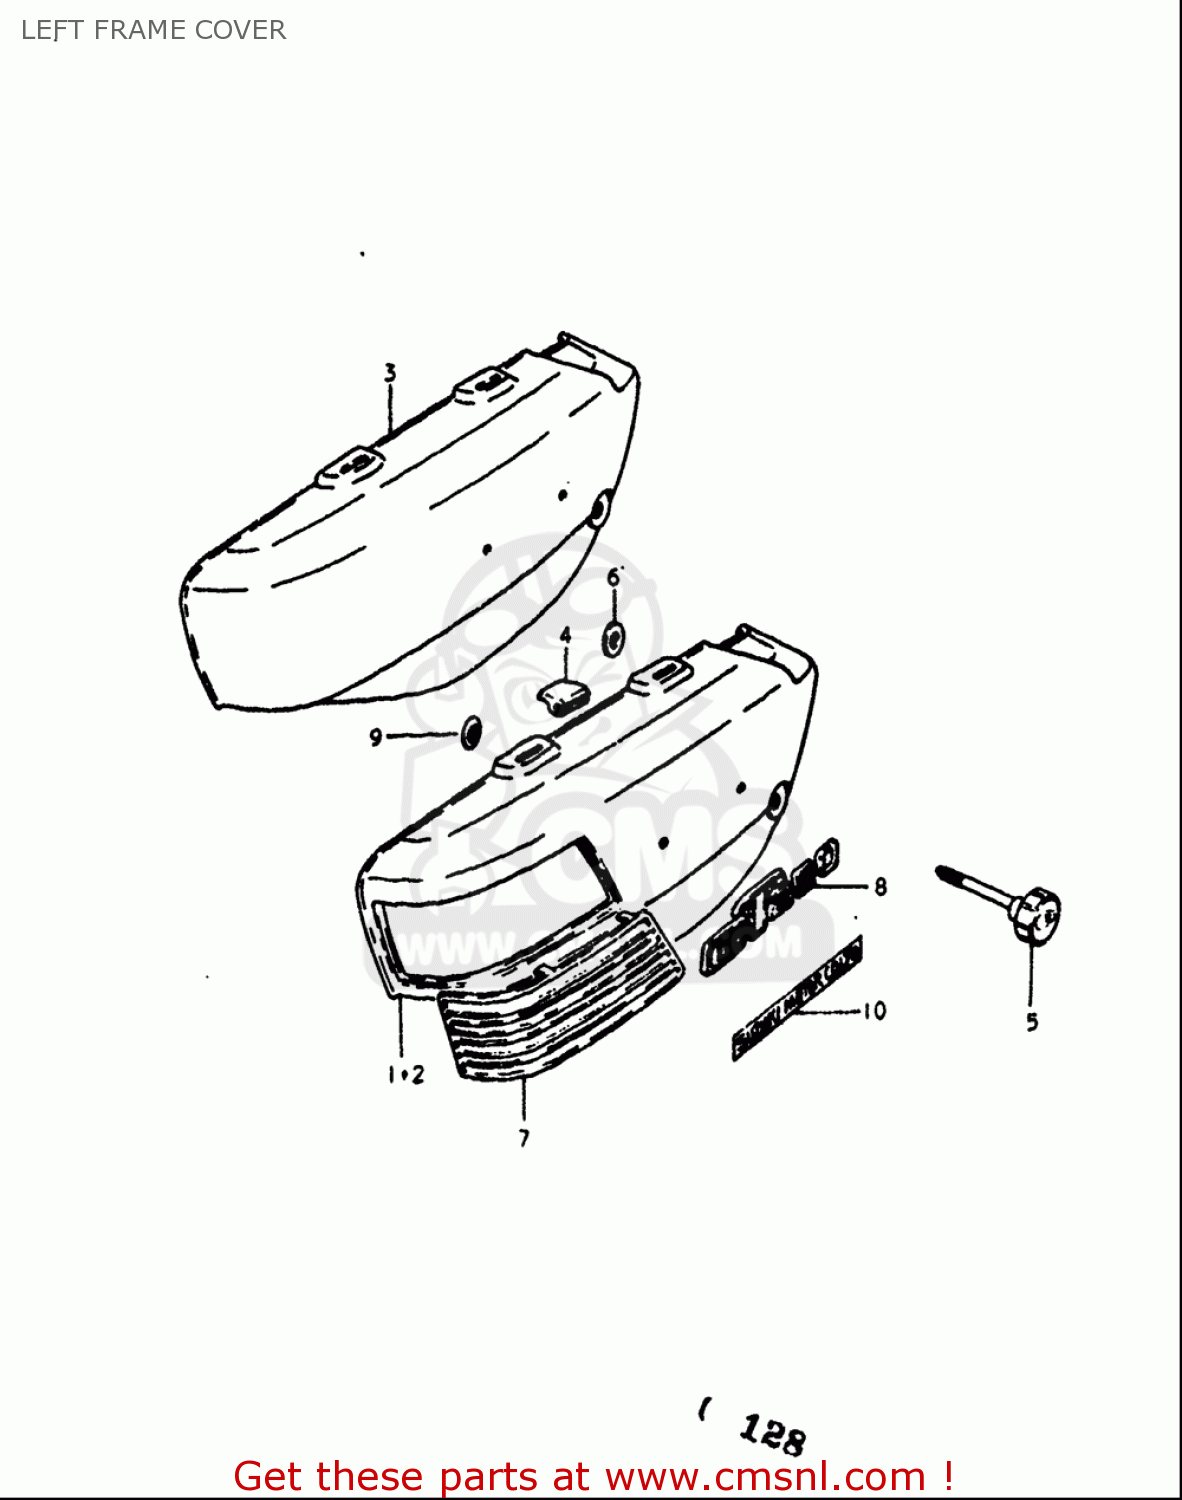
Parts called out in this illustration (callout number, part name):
5	KNOB,FRAME COVER,L
6	NUT
9	NUT
